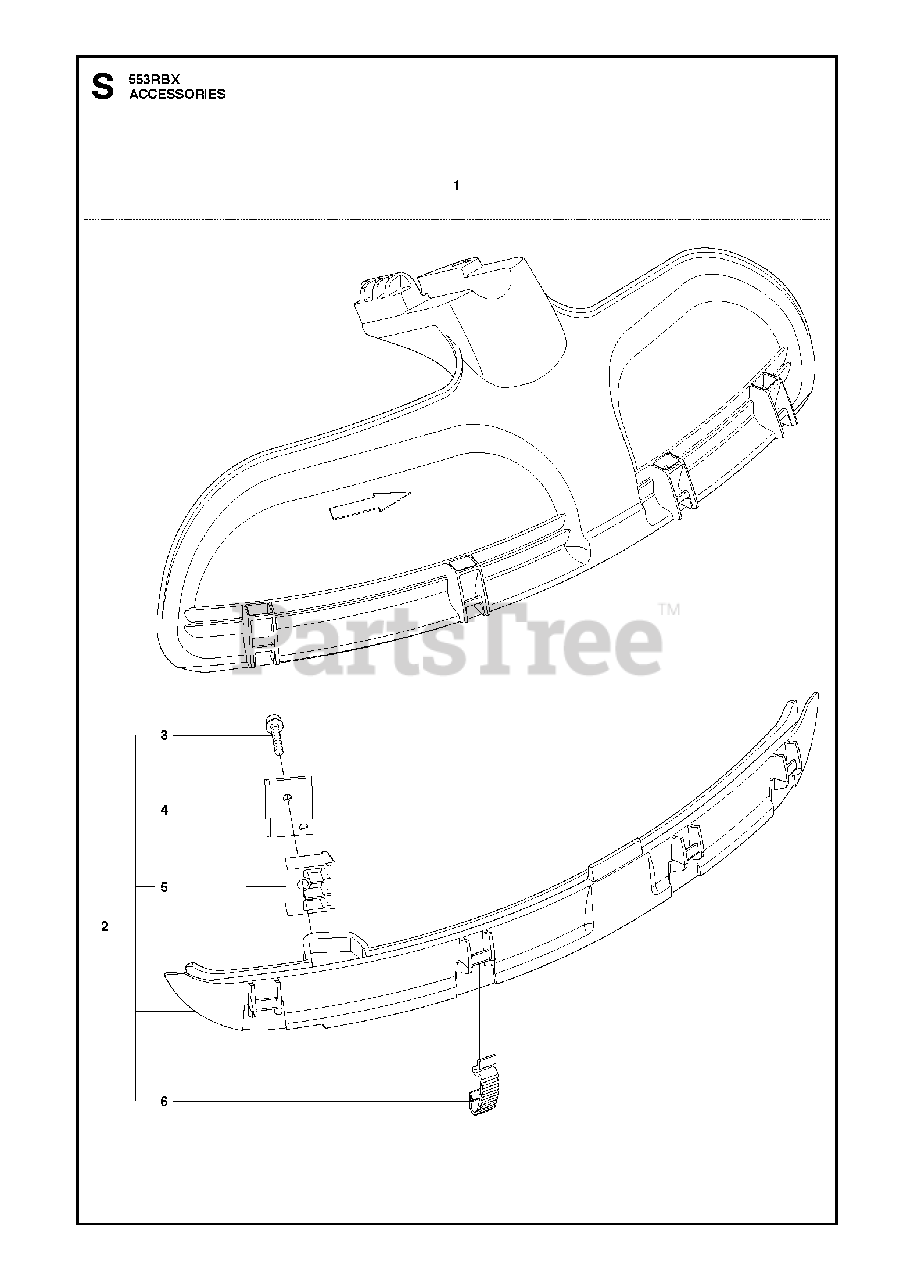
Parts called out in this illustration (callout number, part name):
1	COMBI PROTECTOR
2	SPLASH GUARD
3	SCREW
4	LINE CUTTER
5	DISTANSBLOCK
6	BUCKLE
